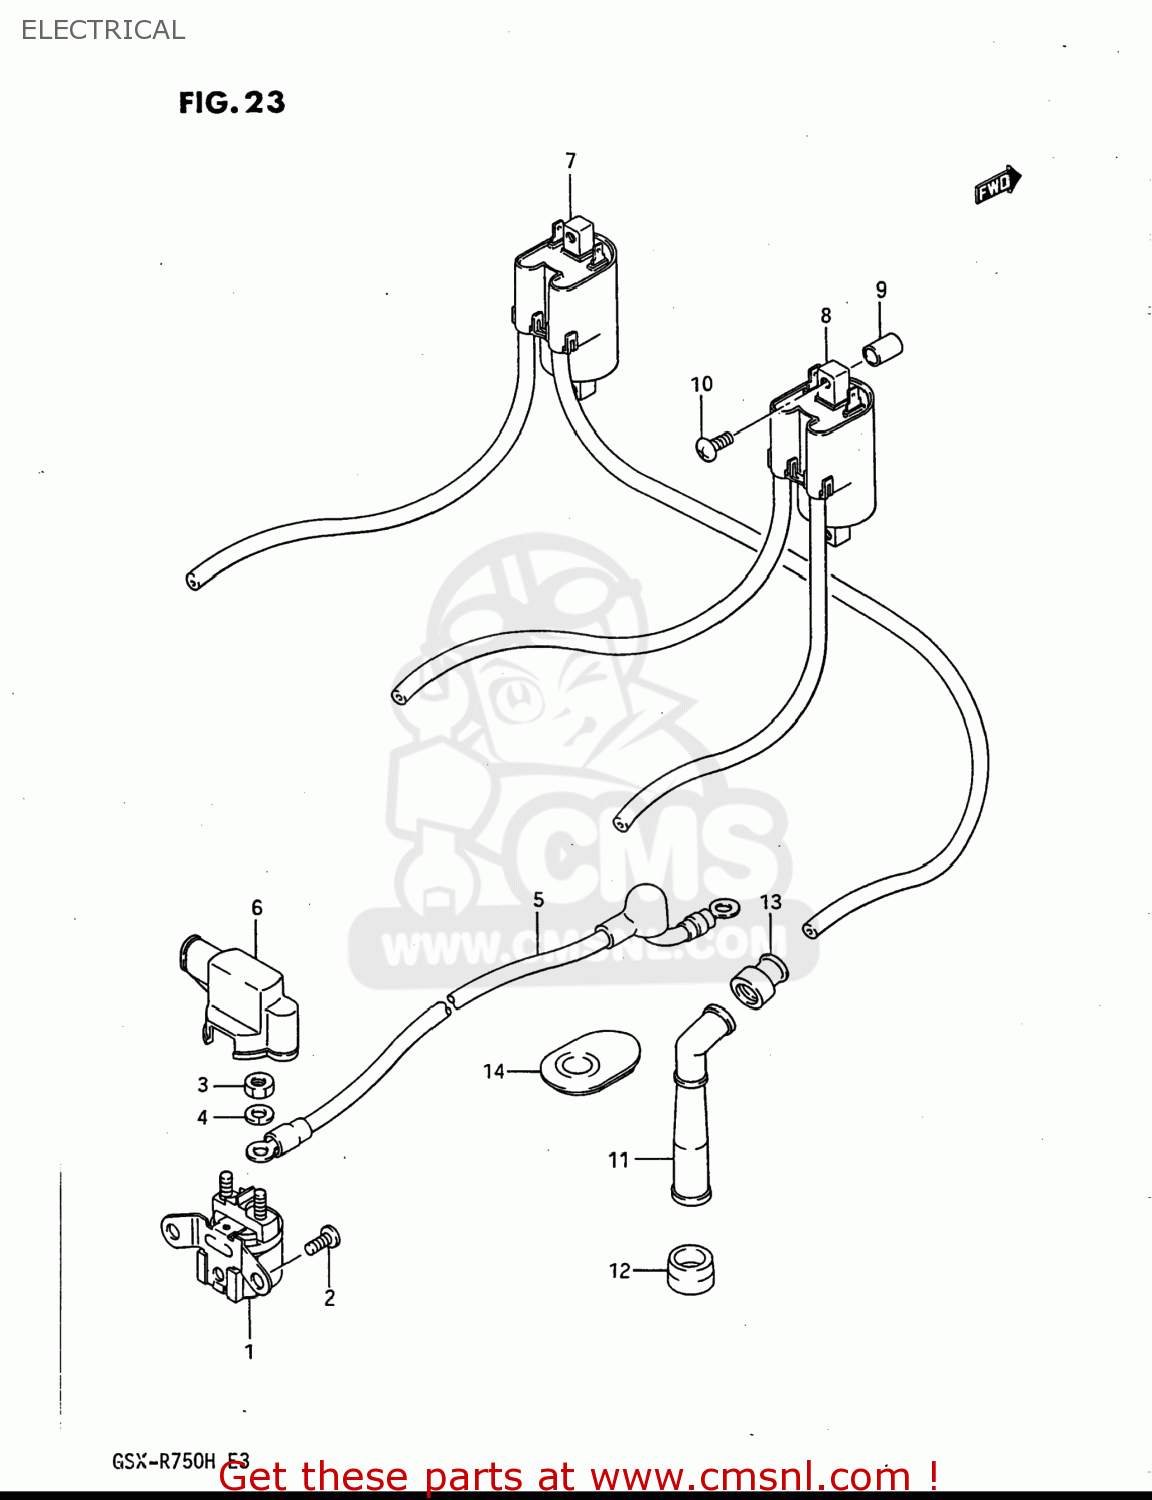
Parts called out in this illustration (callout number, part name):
1	RELAY ASSY,STARTING MOTOR
2	SCREW
3	NUT
4	WASHER,LOCK
5	WIRE,STARTER MOTOR LEAD
6	CAP,STARTER RELAY
7	COIL ASSEMBLY,IGNITION
8	COIL ASSEMBLY,IGNITION
9	SPACER
10	SCREW
11	CAP,SPARK PLUG
12	SEAL,SPARK PLUG
13	SEAL,SPARK PLU
14	COVER,SPARK PLUG CAP
